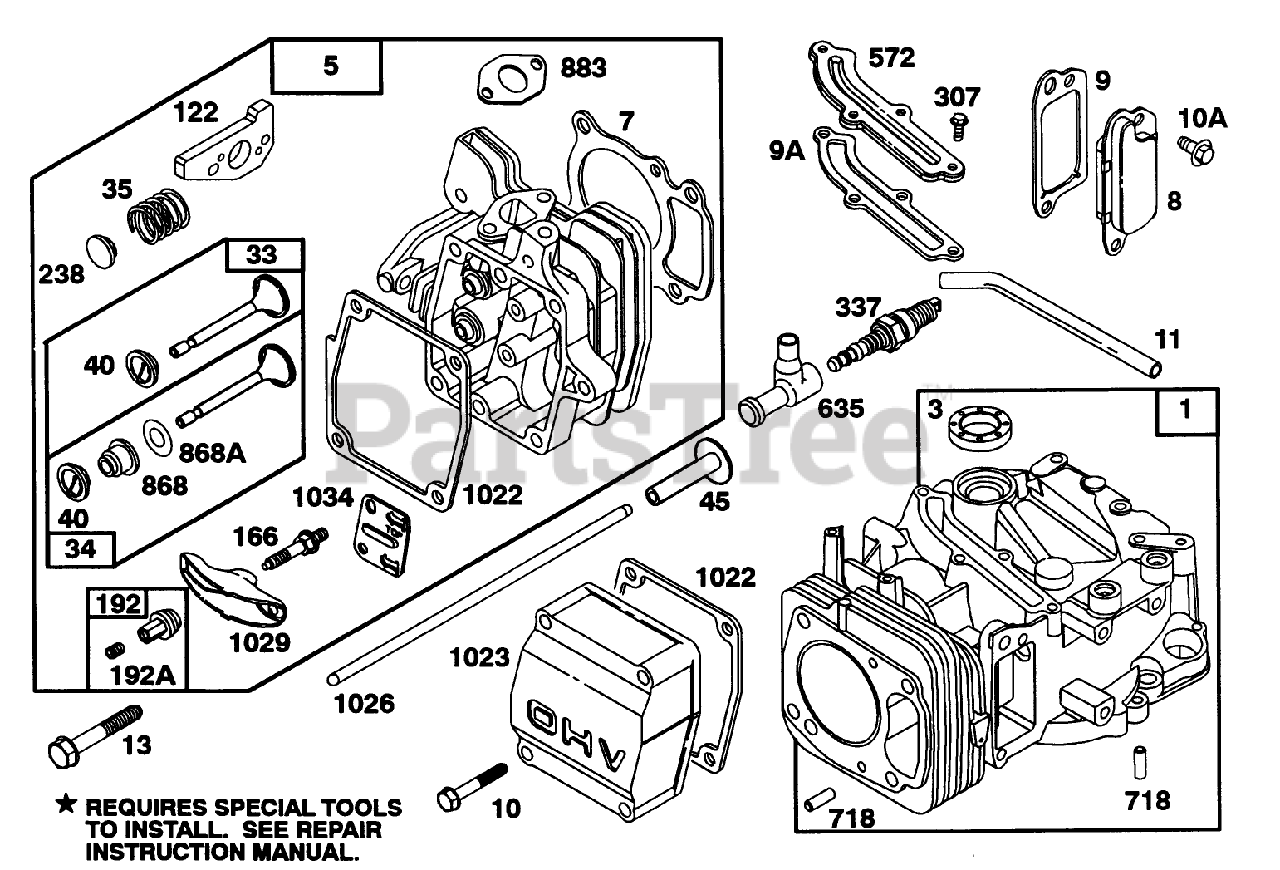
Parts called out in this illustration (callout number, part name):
188	SCREW - SEM
300	MUFFLER - EXHAUST
346	SCREW - SELF-TAPPING
346A	SCREW - ARRESTER MTG.
832	OIL FILLER TUBE
883	EXHAUST GASKET
977	CARBURATOR GASKET SET
994	ARRESTER - SPARK
